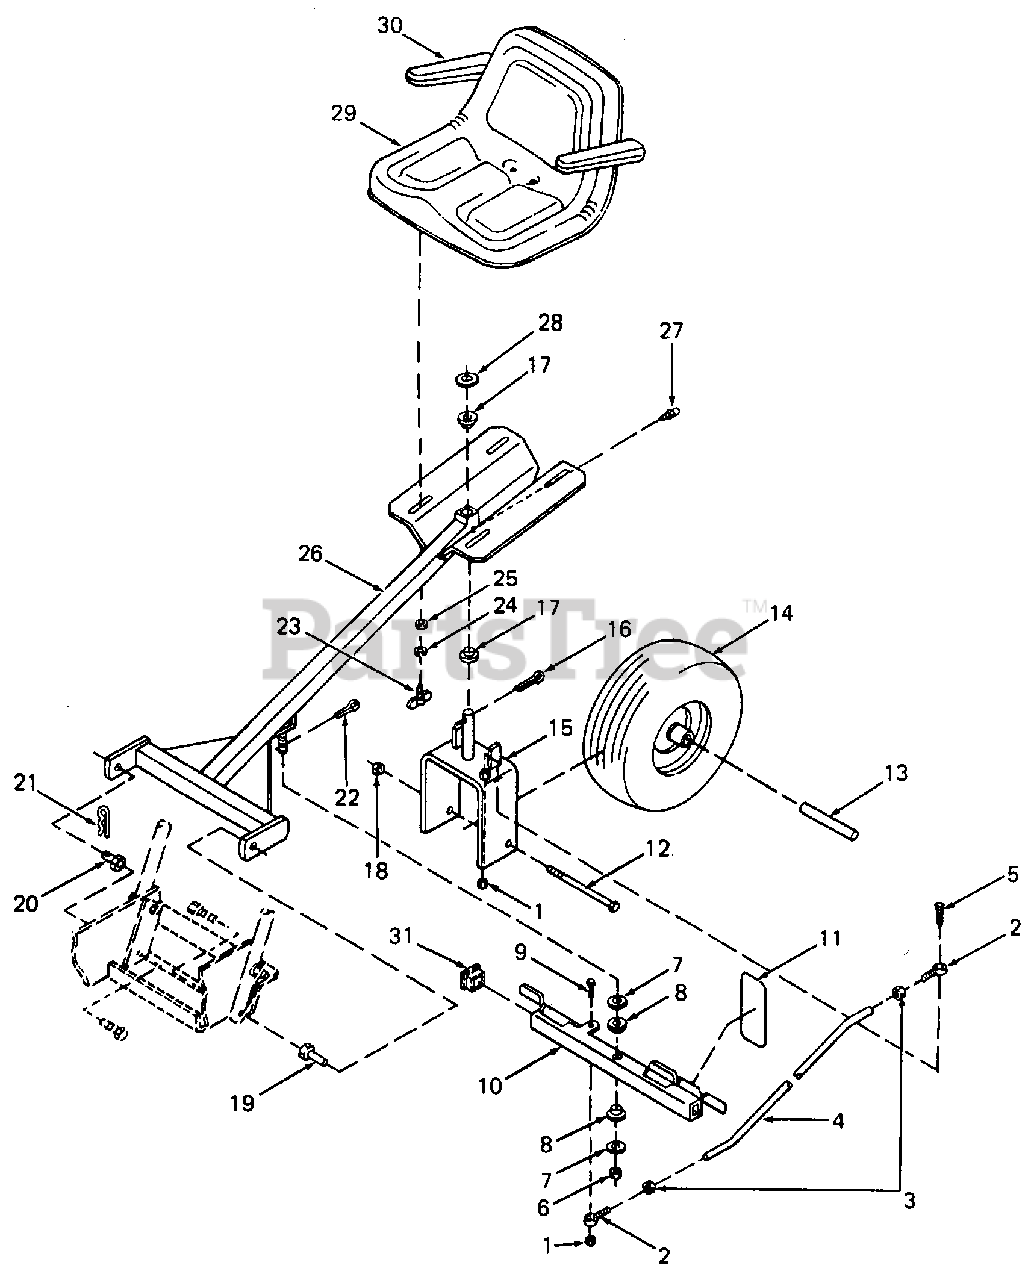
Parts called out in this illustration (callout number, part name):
1	Nut, Lock, 3/8-16
2	Rod End, Male
3	Nut, Jam, 3/8-24
4	Linkage, Steering
5	Bolt, Hex, 3/8-16 X 2.0 GR8
6	Nut, Slotted, 3/4-16 Pltd
7	Washer, Flat, 3/4
8	Bushing, Steering Bar
9	Bolt, Hex, 3/8-16 X 1-1/4 GR5
10	Steering Tube Assembly
11	Pad, Abrasive
12	Bolt, Hex, 1/2-13 X 8-1/2 Pltd GR5
14	Wheel & Tire Assembly
16	Pin, Cotter, Plain, 1/4 X 2.0
18	Nut, Lock, 1/2-13
19	Hitch, Left, Long
20	Hitch, Right, Short
21	Cotter, Hairpin, .18 Dia
22	Pin, Cotter, 1/8 X 1.0 Pln
23	Bolt, Hex, 3/8-16 X 1.0 Zn GR5
24	Washer, Spring Lock, 3/8
25	Washer, Flat, 3/8
26	Sulky Frame
27	Fitting, Gr, 1/4-28 Str Short
28	Washer, Flat, 1 Dia Narrow Zn
30	Arm Rest Kit
